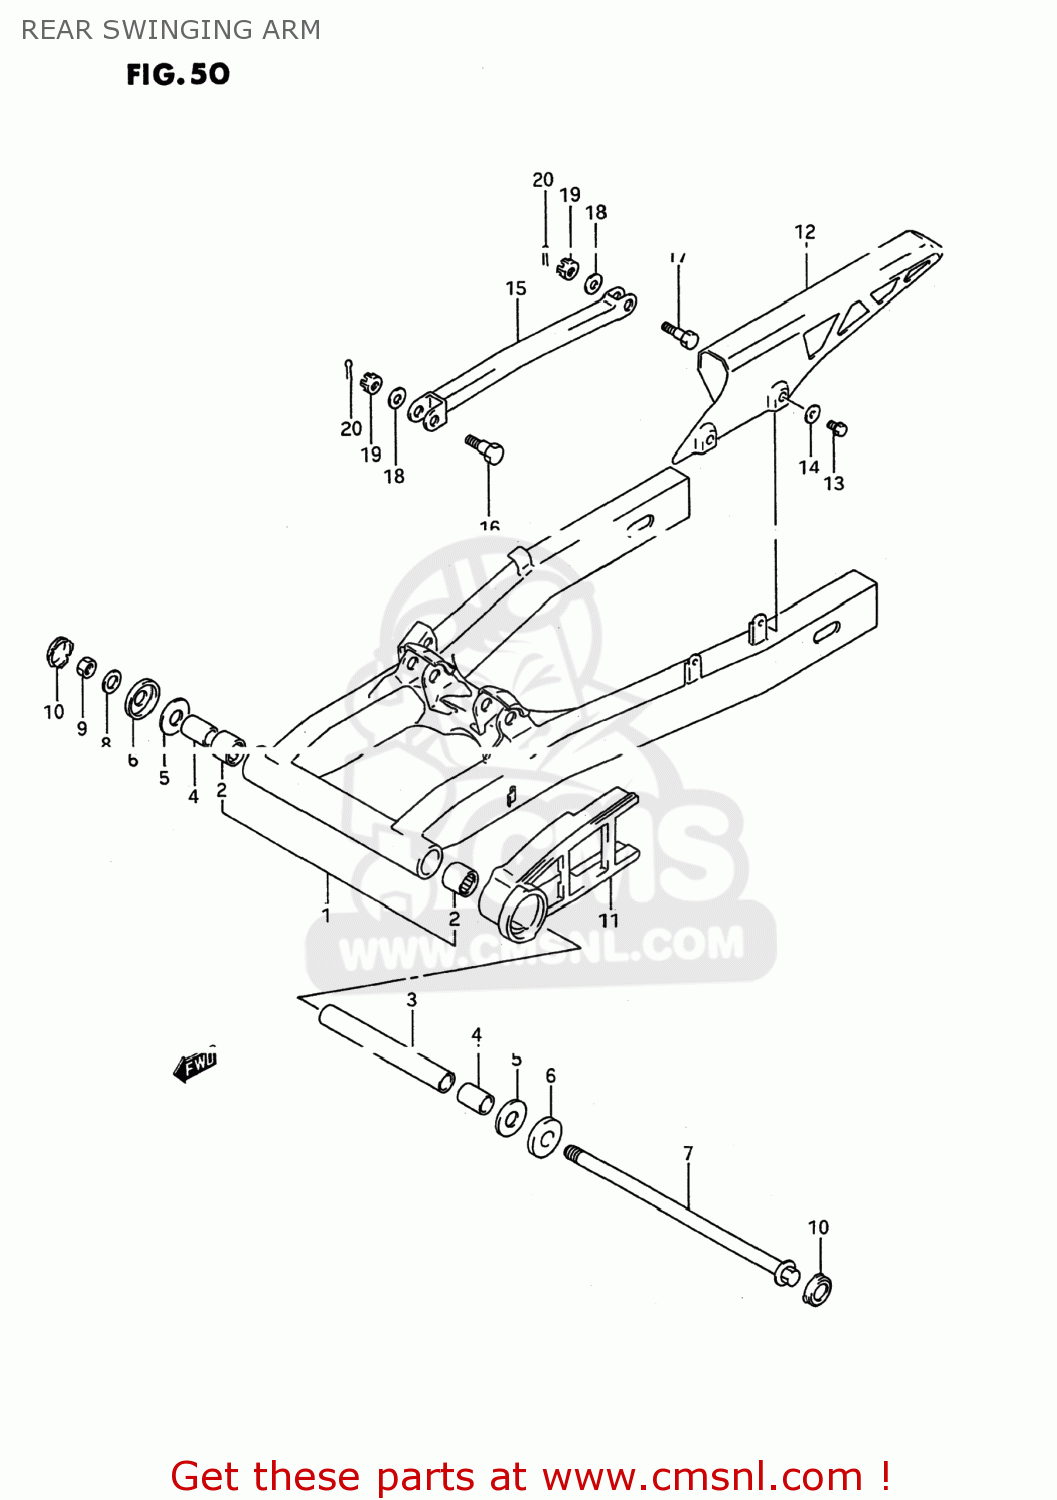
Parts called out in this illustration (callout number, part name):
1	SWINGINGARM ASSY,RR
2	BEARING(22X29X30)
3	SPACER,RR SWGARM PIVOT CTR
4	SPACER,RR SWGARM PIVOT
5	WASHER
6	CVR,RR SWGARM DUST SEAL(OD:40)
7	SHAFT,REAR SWING ARM PIVOT
8	WASHER(14X27X3)
9	NUT
10	CAP,SWINGINGARM PIVOT
11	BUFFER,CHAIN TOUCH DEFENSE
12	CASE,CHAIN
13	BOLT
14	WASHER
15	TORQUE LINK,REAR
16	BOLT(10X41)
17	BOLT(10X35)
18	WASHER (10X18X3.2)
19	NUT
20	PIN 20X20
